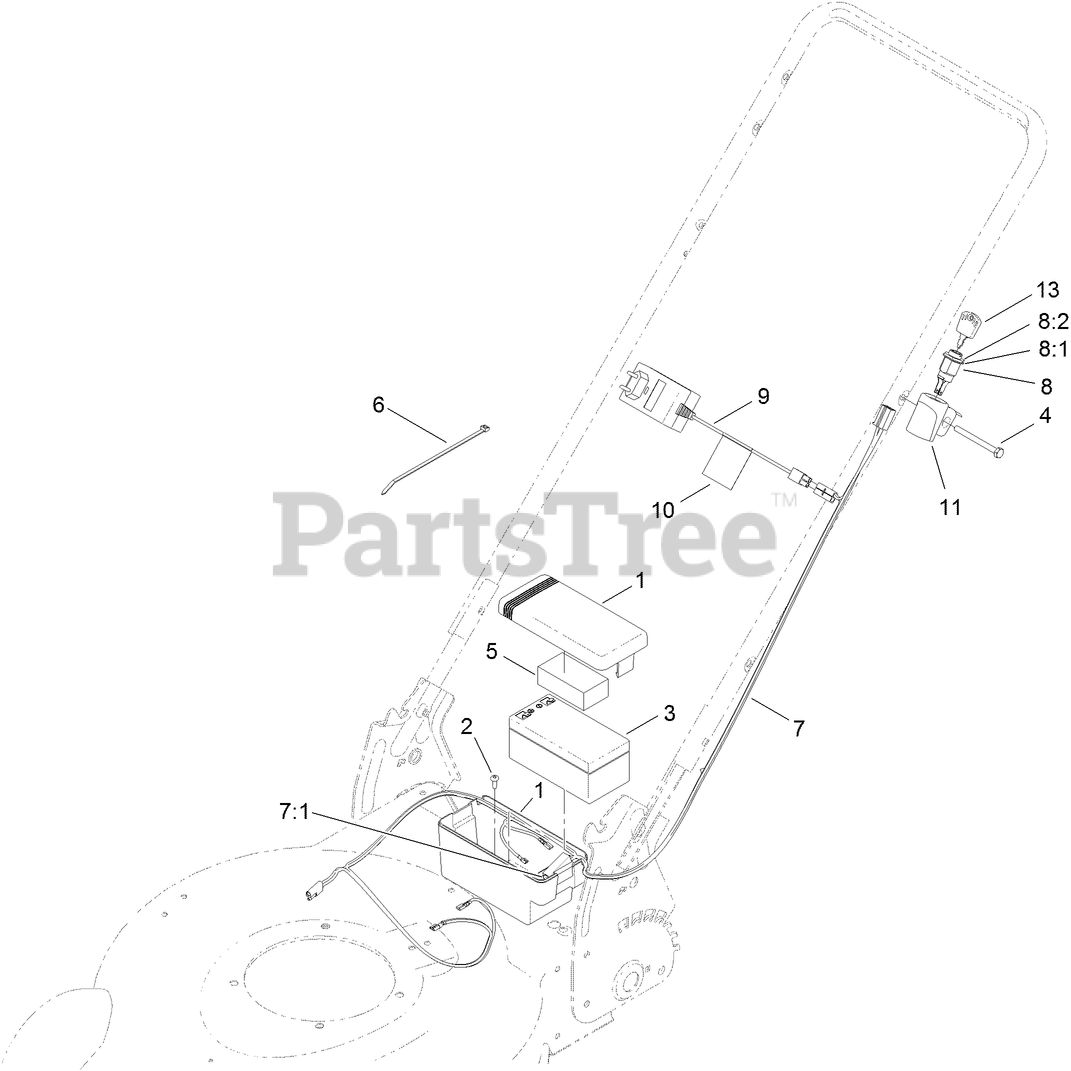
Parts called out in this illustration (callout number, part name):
1	BATTERY BOX ASM
2	SCREW-FORMING, THREAD
3	BATTERY-WET
4	SCREW-HH
5	FOAM-BATTERY, TOP
6	TIE-CABLE
7	HARNESS-WIRE
7:1	FUSE-40 AMP
8	STARTER SWITCH ASM
8:1	WASHER-LOCK
10	DECAL-WARNING
11	MOUNT-SWITCH
